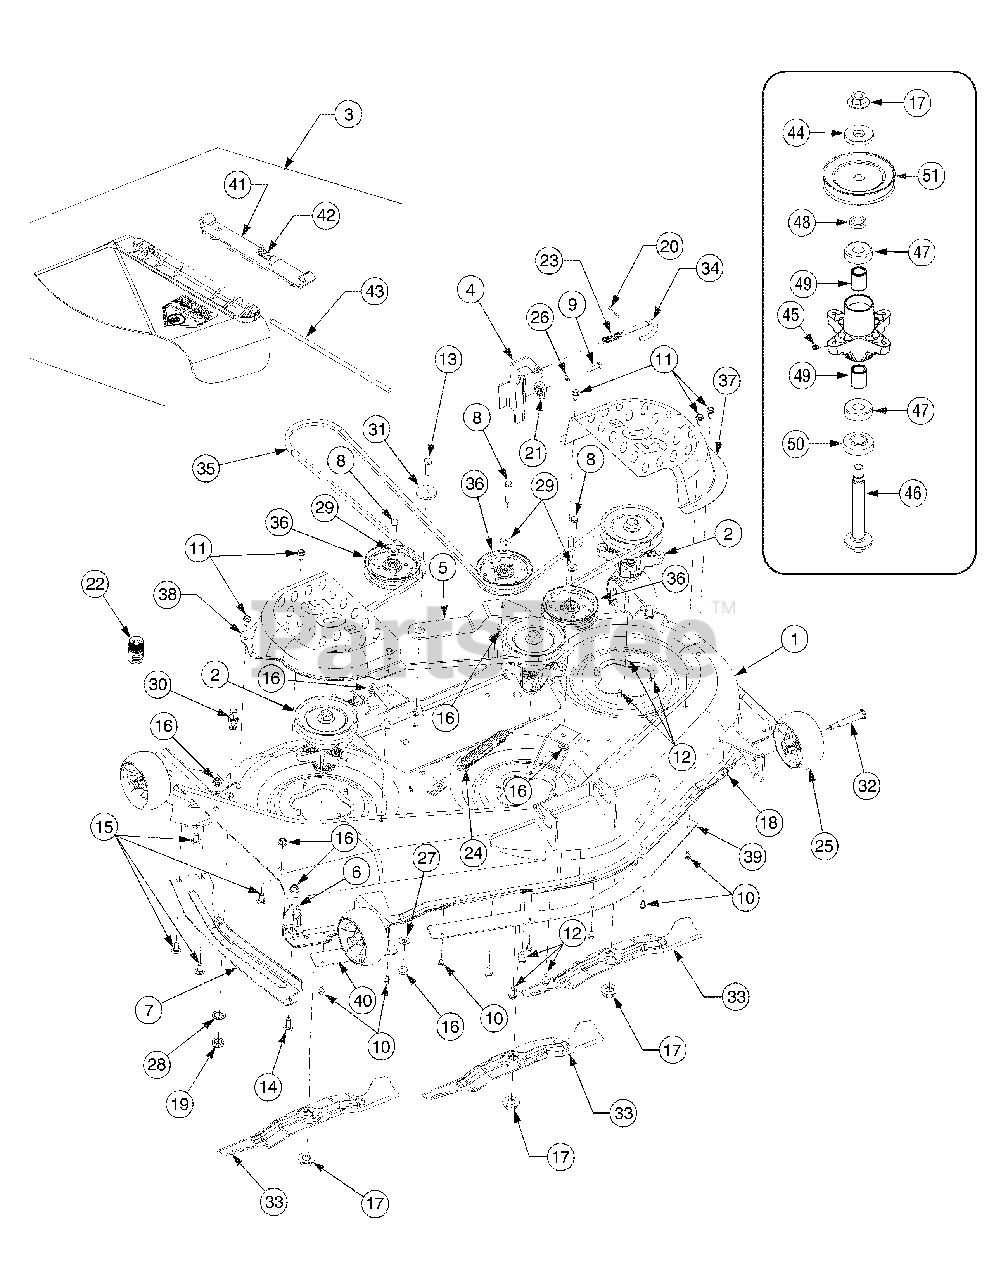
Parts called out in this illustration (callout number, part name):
2	Spindle Assembly
3	Discharge Chute Ass’y
7	Guard, Finger
8	Hex Screw 3/8-16 x 1.75
9	Hex Bolt 5/16-18 x 1.25
10	Hex Wash S-Tapp Scr 1/4-20 x .50
11	Hex Wash HD AB Scr 5/16-12 x .75
12	Hex Wash. Hd. Scr. 5/16-18 x .75 Lg.
13	Hex Bolt 3/8-16 x 1.25
14	Carriage Bolt 3/8-16 x 1" Lg. Gr. 5
15	Short Neck Car riage Bolt 3/8-16 x .75
16	Flange Lock-Nut 3/8-16 Gr. F Nylon
17	Hex Flange Nut 5/8-18
18	Hex. Flanged L-Nut 3/8-16 Gr. F
19	Hex Nut M16-1.5 DIN 936
20	Cotter Pin 1/8" Dia x 1.25
21	Deck Adjustment Gear
22	Water Nozzle Adaptor
23	Comp. Spring .531 OD x 1.75 Lg.
24	Extension Spring .94 OD x 6.74
25	Deck Wheel 5.0
26	L-Wash 5/16 ID
27	Cupped Washer .45 x 1.0 x .062
28	L-Washer Internal
29	Flat Washer .38 x .93 x .11
30	Port, Water
31	Shoulder Spacer .884 x .190
32	Shoulder Screw, 1/2 Diameter x 2.5
33	Blade 17.9" Lg.
34	Deck Release Pin
35	V-Belt Type A Sec x 134
36	Idler Pulley w/Flange 4.25 Dia
41	Chute Mounting Bracket
42	Torsion Spring
43	Hinge Pin
44	Flat Washer .76 ID x 1.5 OD x .12
45	Grease Fitting
46	Spindle Shaft 5.75 Lg.
47	Ball Bearing 20 x 47 x 14:6204:DS
48	Spacer .79 x 1.25 x .175
49	Spacer .080 x 1.10 x 1.322" Lg.
50	Spacer .79 x 1.82 x .55
51	Spindle Pulley
